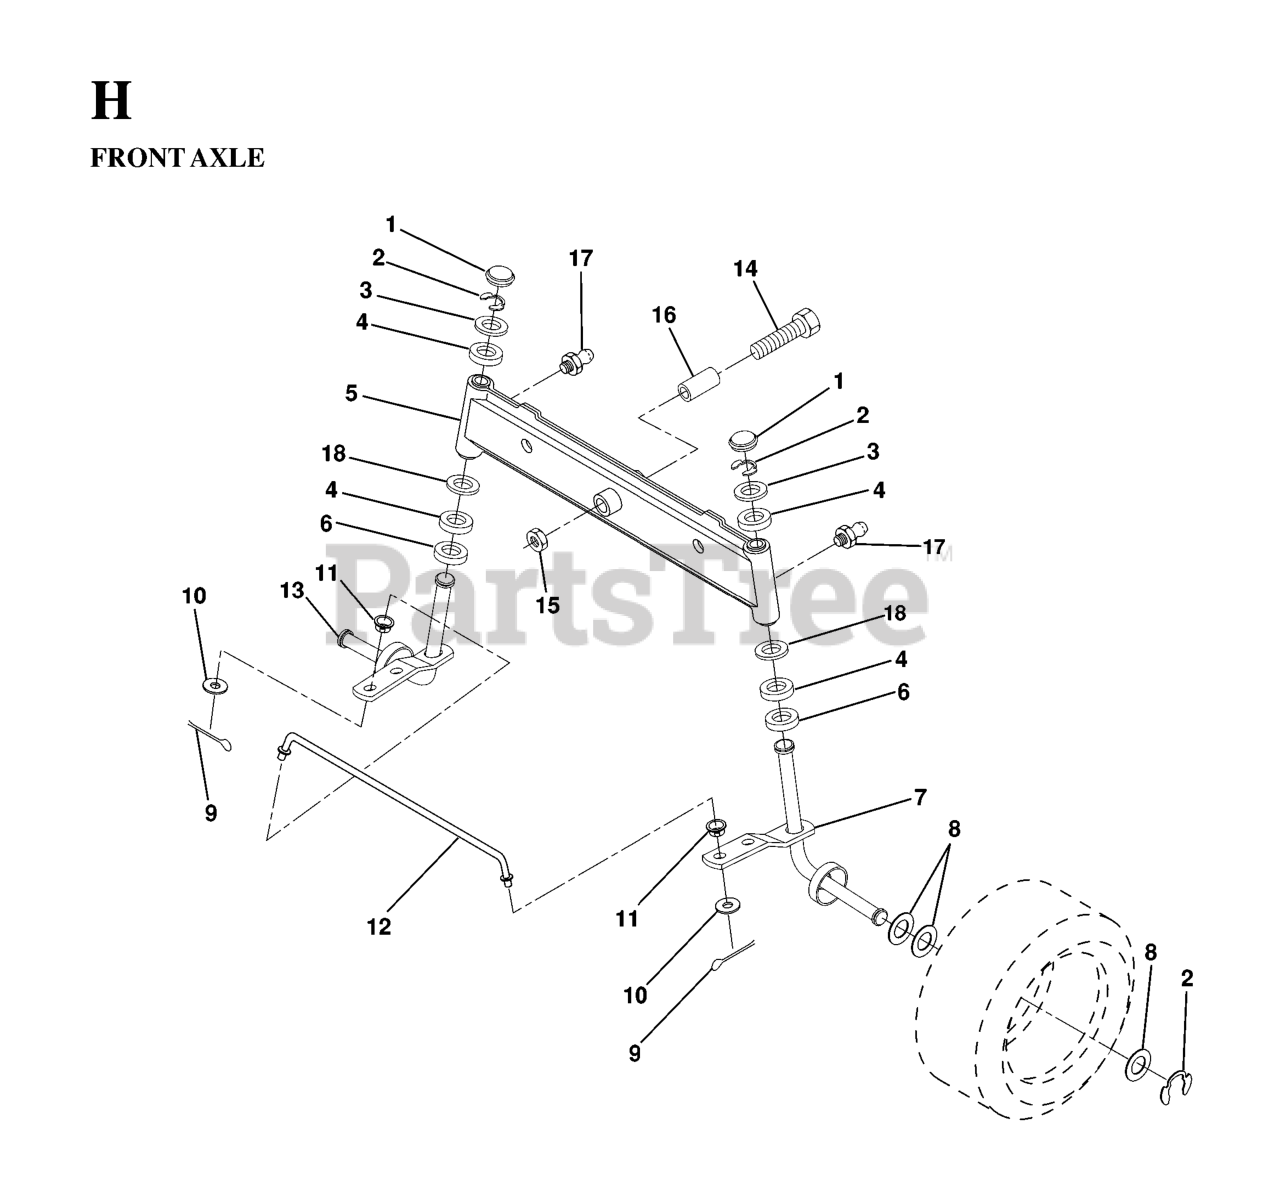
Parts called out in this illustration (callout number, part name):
1	CAP.SPINDLE.BLACK
4	BRNG T
6	THRUST WASHER
7	SPINDLE ASSY RH NLA
9	COTTER PIN
10	WASHER
11	BUSHING.DRAGLINK (2 2)
12	TIE ROD
13	SPINDLE ASSY LH
14	Bolt, Hex Head 5/8-11 x 3-1/2
15	NUT-LOC,FLANGE LT
16	BEARING
17	ZERK M
